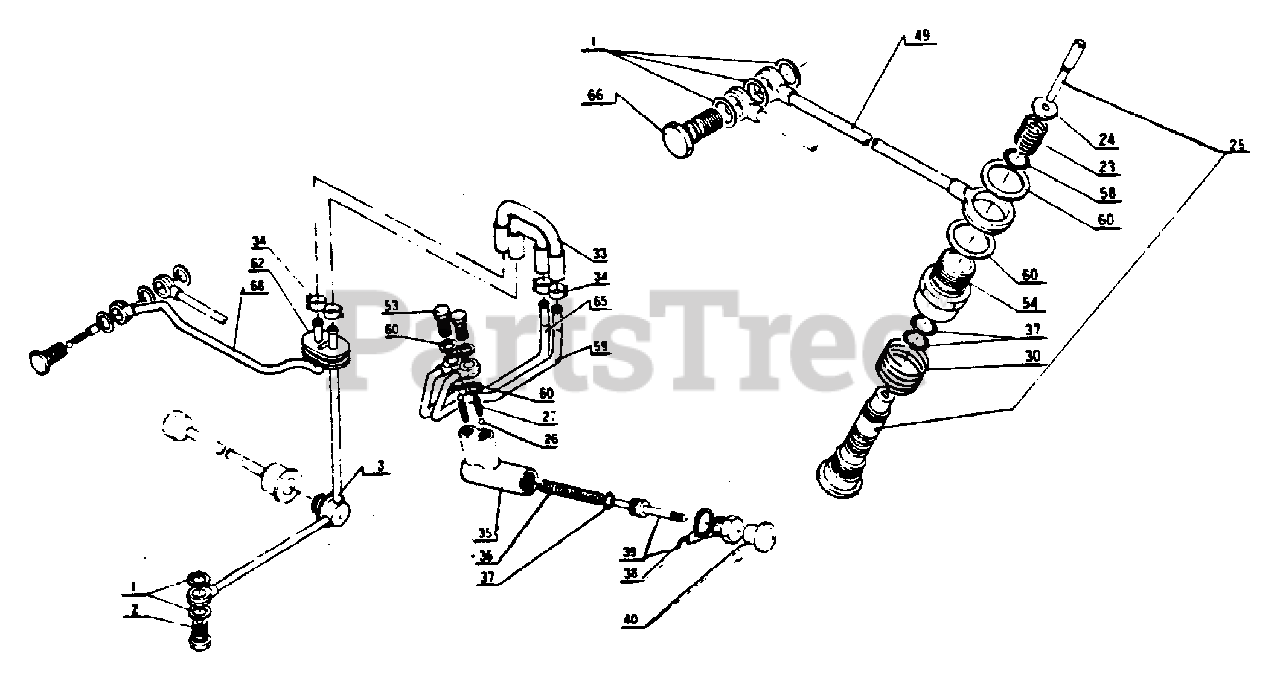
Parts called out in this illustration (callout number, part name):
1	GASKET
2	HOLDING BOLT
3	PIPE, OIL
23	SPRING
24	SPRING CASE
25	CYLINDER, OIL
26	VALVE, BALL
27	SPRING, VALVE
30	SPRING
33	PIPE, OIL
34	CLIP
35	BODY, OIL PUMP
36	SPRING, OIL PUMP
37	O-RING
38	WASHER, LOCK
39	PISTON, OIL PUMP
49	PIPE, OIL
53	HOLDING BOLT
54	NUT, ADJUST
58	O-RING
59	PIPE, OIL
60	PACKING
62	GROMMET
65	PIPE, OIL
66	HOLDING BOLT
68	PIPE, OIL
